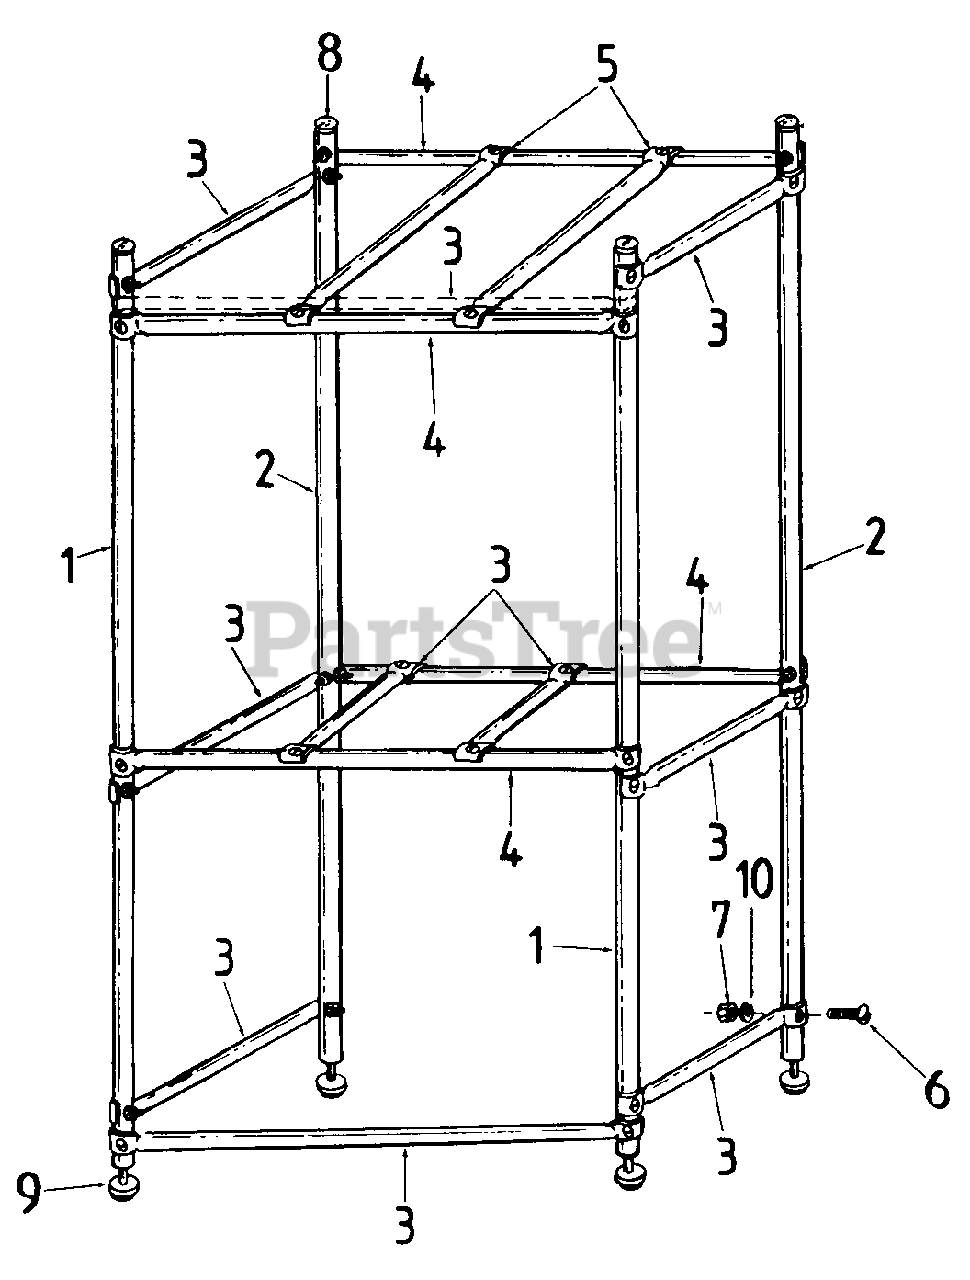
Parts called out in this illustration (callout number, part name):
3	Cross Brace w/o Center Holes 31 " Lg.
6	Truss Mach. Screw 1/4- 20 x 1-1/2" Lg.
7	Hex Nut 1/4-20 Thd.
8	1" Tubing Plug
9	1" Swivel Glide
10	Lock Washer 1/4" I.D.
